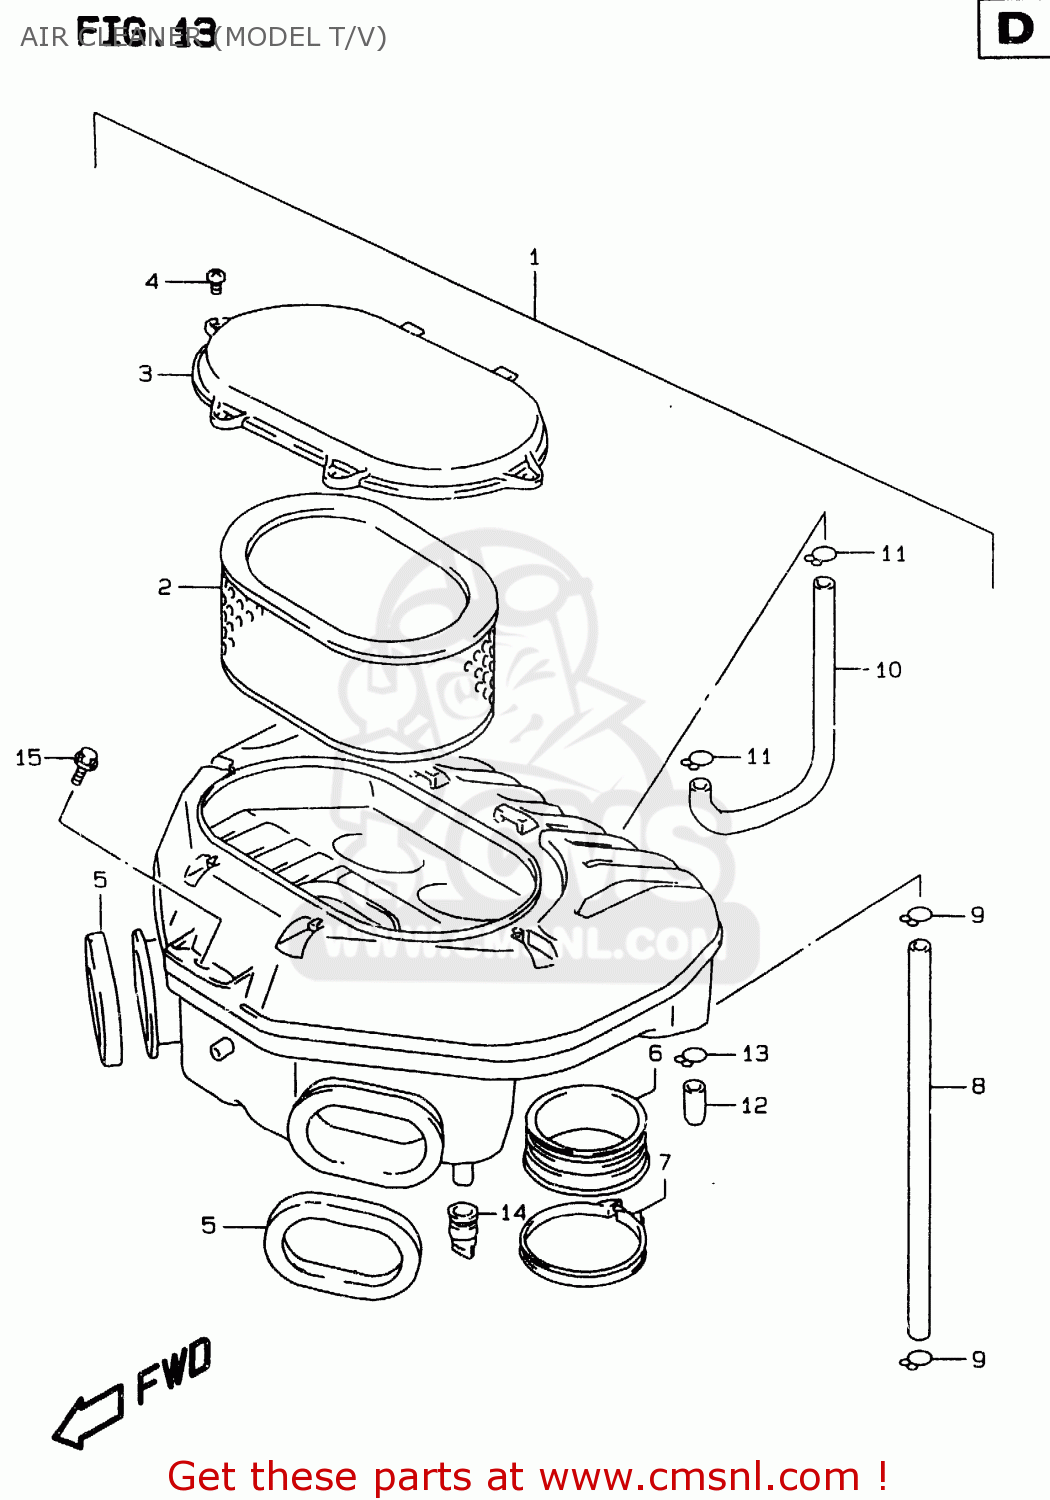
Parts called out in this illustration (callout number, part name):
1	CLEANER ASSY,AIR
2	FILTER,AIR CLEANER
3	CAP,AIR CLEANER
4	SCREW 5X12
5	CUSHION,DUCT
6	TUBE,OUTLET
7	CLAMP
8	TUBE,BREATHER
9	CLIP
10	TUBE,CONTROL AIR
11	CLIP
12	PLUG
13	CLIP
14	CAP,DRAIN
15	BOLT
